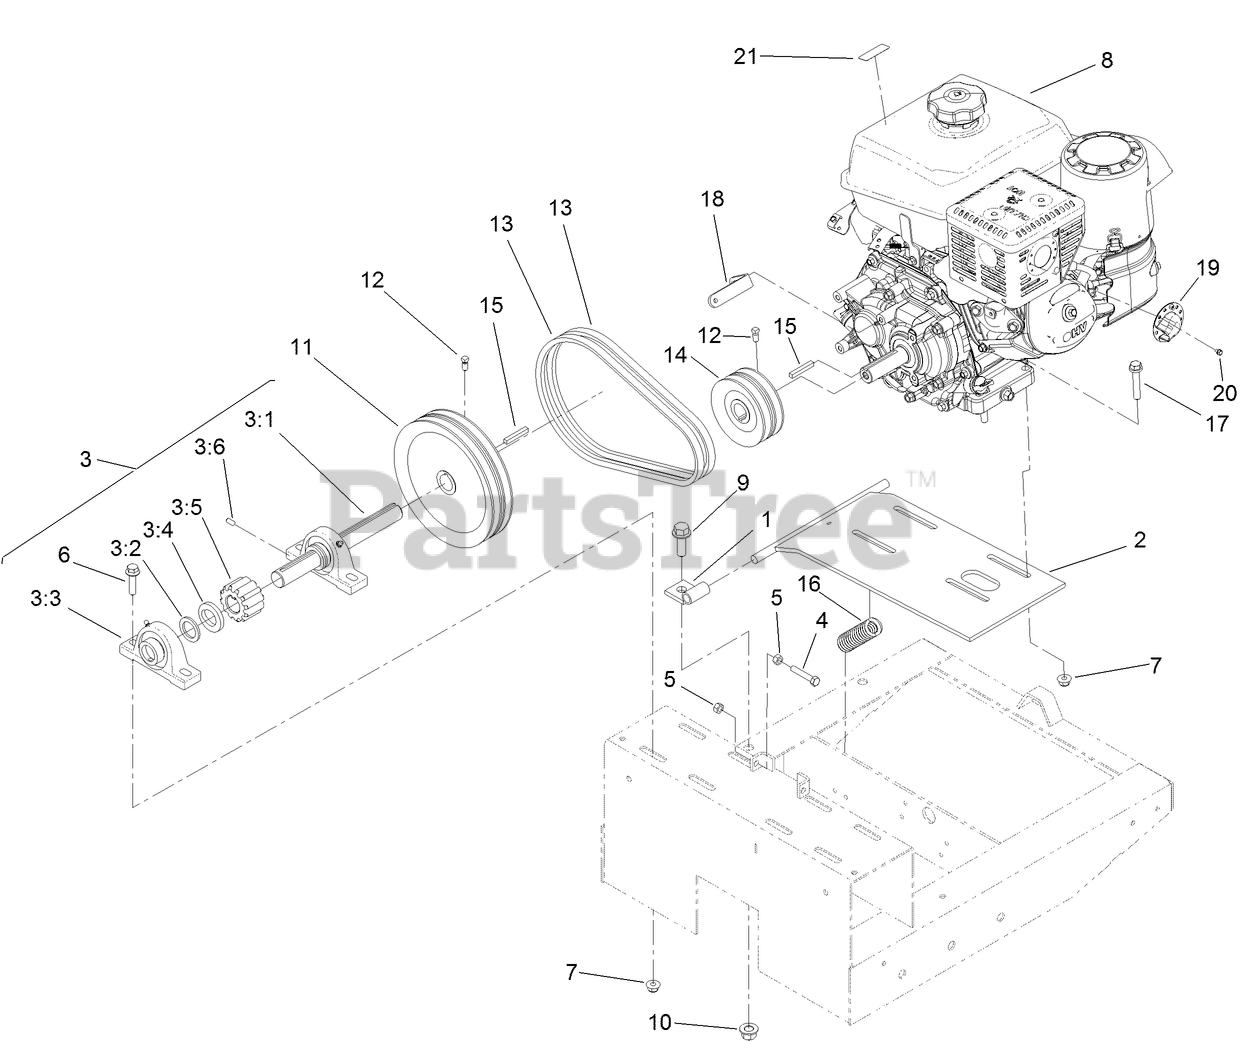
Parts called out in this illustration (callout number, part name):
1	MOUNT-MOTOR
2	BASE-MOTOR
3	PINION ASM
3:2	WASHER-THRUST
3:3	BEARING-BLOCK, PILLOW
3:4	WASHER
3:5	GEAR-SPUR
3:6	PIN-DOWEL
4	SCREW-HH
5	NUT-HEX
6	SCREW-HHF
7	NUT-HF, NI
8	ENGINE-HONDA, GX240
9	SCREW-HHF
10	NUT-LOCK
11	SHEAVE
12	SCREW-SET
13	BELT-V (MATCHED PAIR)
14	SHEAVE
15	KEY-SQUARE
16	SPRING
17	SCREW-HHF
18	GUIDE-BELT
19	DEFLECTOR-EXHAUST, HONDA
20	SCREW-HWH
21	DECAL-WARNING, ETHANOL
